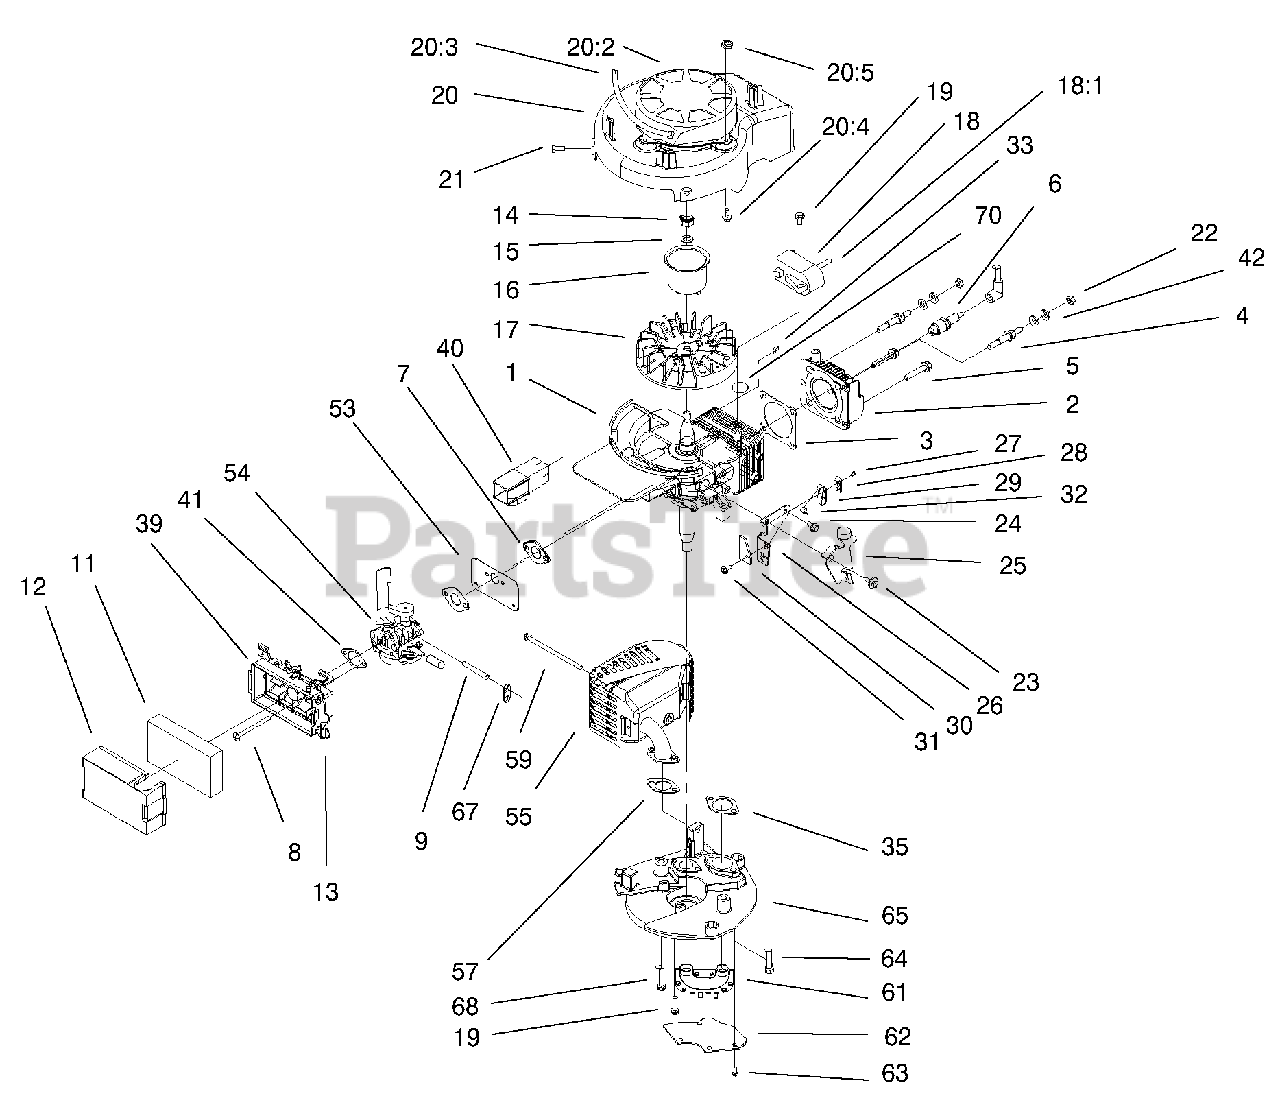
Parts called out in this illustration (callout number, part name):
1	Short Block ASM
1	SHORT BLOCK ASM
2	HEAD-CYLINDER
3	GASKET-HEAD
5	BOLT-HEAD
6	SPARK PLUG
7	GASKET-INTAKE
9	HOSE-PRIMER
11	FILTER-AIR
12	COVER-FILTER, AIR
13	RETAINER-COVER, FILTER
15	WASHER-LOCK
16	CUP-STARTER
17	FLYWHEEL
18	MODULE-IGNITION CD
18:2	LEAD-TENSION, HIGH
20	SHROUD-RECOIL
20:2	RECOIL ASM
20:4	SCREW-HWH
20:5	NUT-LOCK
21	SCREW-HH
23	SCREW-SHOULDER
24	SCREW-HWH
25	BRAKE PLATE AY EV
26	PLATE-BRAKE
27	RIVET-PLASTIC
28	STRAP-INSULATION
29	STRAP-GROUND
30	STOP-STRAP, GROUND
32	LEAD WIRE-SWITCH, BRAKE
35	GASKET-EXHAUST
39	AIR BASE ASM
40	TUNNEL-INLET
41	GASKET-FILTER
42	WASHER-BELLEVILLE
53	SHIELD-CARB E
54	CARBURETOR ASM
54	Carburetor Asm
55	MUFFLER & GUARD AY E
59	BOLT-CONSOLE
61	PIPE-TRANSFER
62	COVER-MUFFLER E
63	SCREW-HH
64	SCREW-HH
65	PLATE-MUFFLER E MACH
67	HOSE-RETAINER
68	SCREW-HH
70	STRAP-TIE
